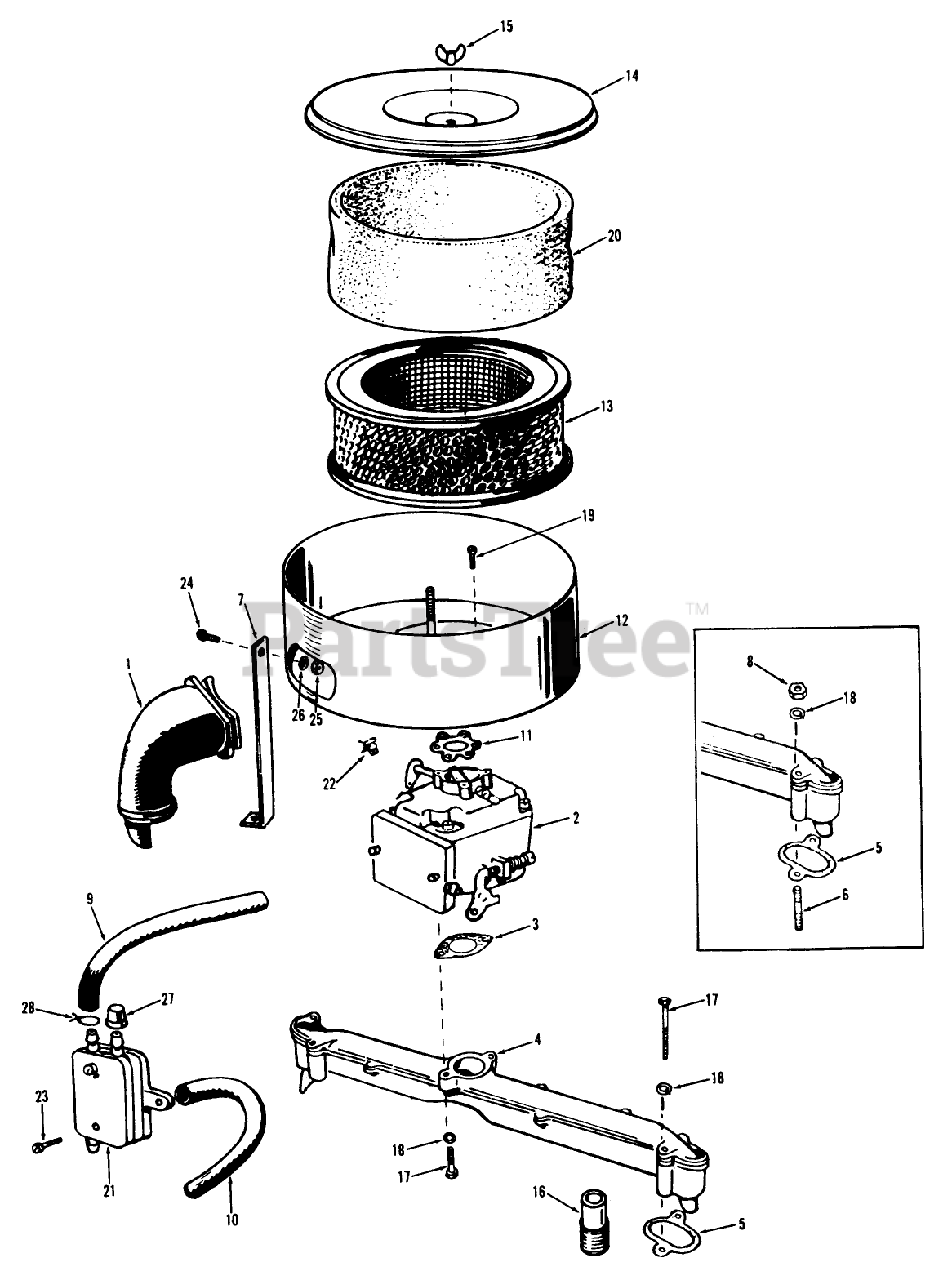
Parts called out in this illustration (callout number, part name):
3	Carburetor Mounting Gasket
6	Stud-Intake Manifold
8	Nut-Intake Manifold
9	Hose-Fuel Pump To Carburetor
10	Hose-Fuel Pump Vacuum
13	ELEMENT-AIR CLEANER
15	Wing Nut-Air Cleaner Cover
16	Nipple, (1" x 2 1/2")-Exhaust
17	Hex Bolt-Intake Manifold Mounting
18	Intake Manifold Mounting (5/16")
18	Carburetor Mounting (1/4")
19	SCREW-RD HD10-32X3/8
21	Fuel Pump
24	Hex Bolt 1/4-20 X 1/2
25	Hex Nut 1/4-20
26	Lockwasher
28	Clamp, Hose (7/16")
